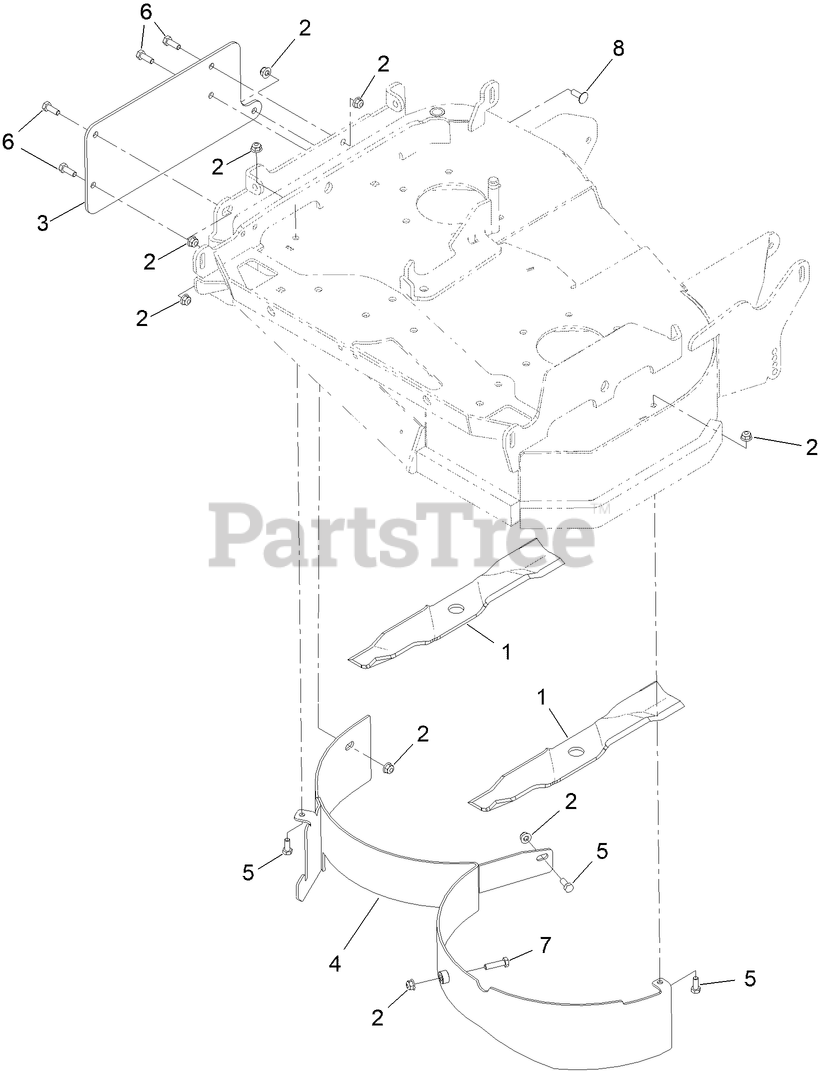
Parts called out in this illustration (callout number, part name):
1	BLADE, RECYCLER 16.25 (.94 HOLE)
2	NUT-HF, NI
3	PLATE, MULCH COVER
4	WLD FRONT 32 BAFFLE
5	SCREW-HH
6	SCREW-HH
7	SCREW-HH
8	BOLT-CARR
